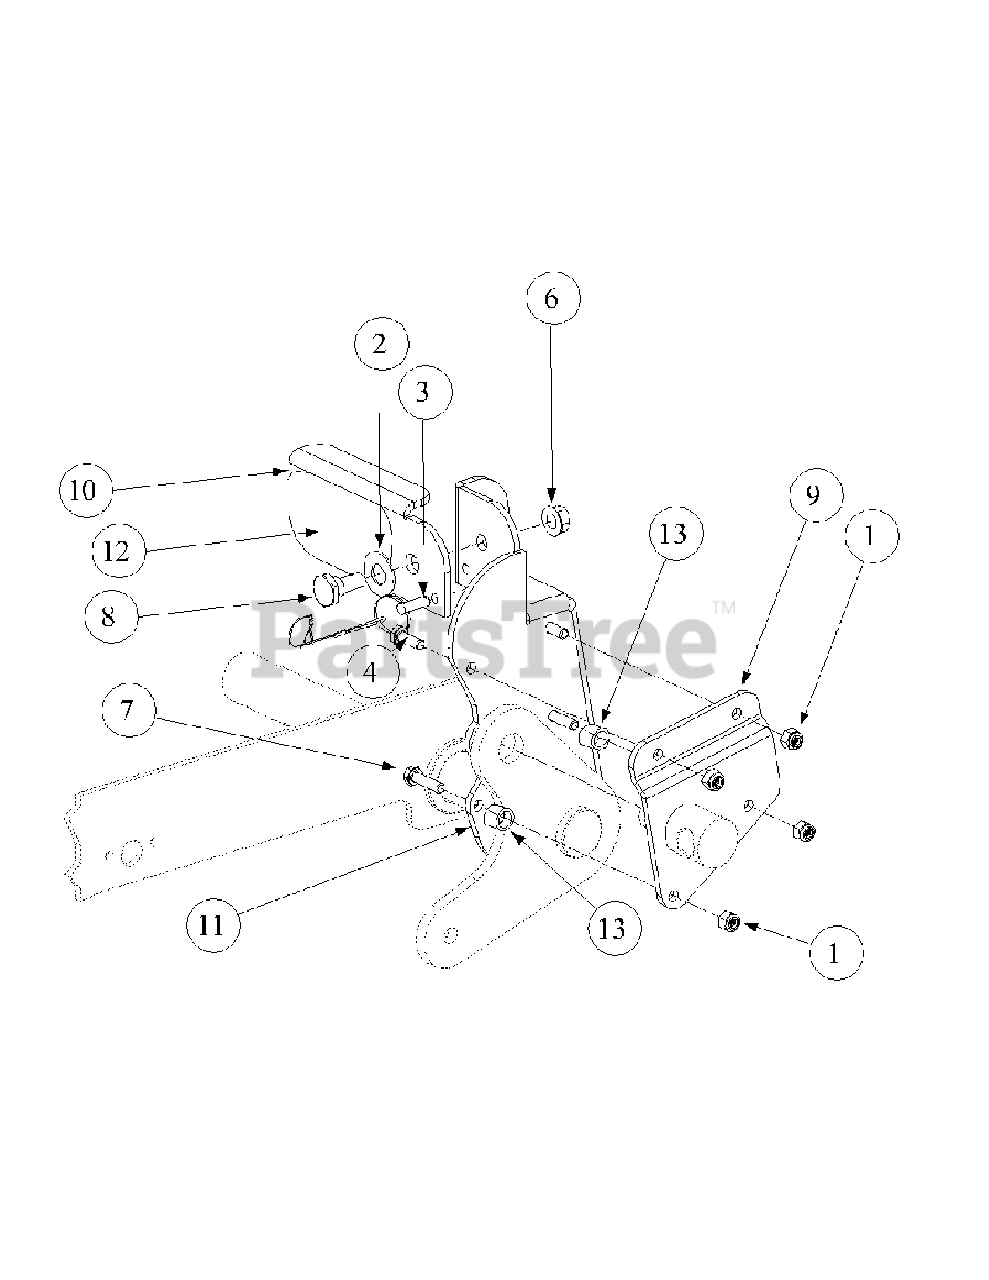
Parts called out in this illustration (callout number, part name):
1	Lock Nut, Nylon Insert, 1/4-20
2	Washer, 1/2 x 1 Shim
3	Detent Pin w/12" Lanyard
4	Hex Cap Screw, 1/4-20, .75
6	Hex Nut, Flange Lock 3/8-16
7	Hex Cap Screw, 1/4-20, 1.00
8	Shoulder Screw, .50 x .27 Lg., 3/8-16
9	Foot Lift Backup Pedal
10	Deck Foot Pedal Lift
11	Deck Foot Pedal Lift
12	Deck Foot Lift Pad
13	Turnbuckle Sleeve
